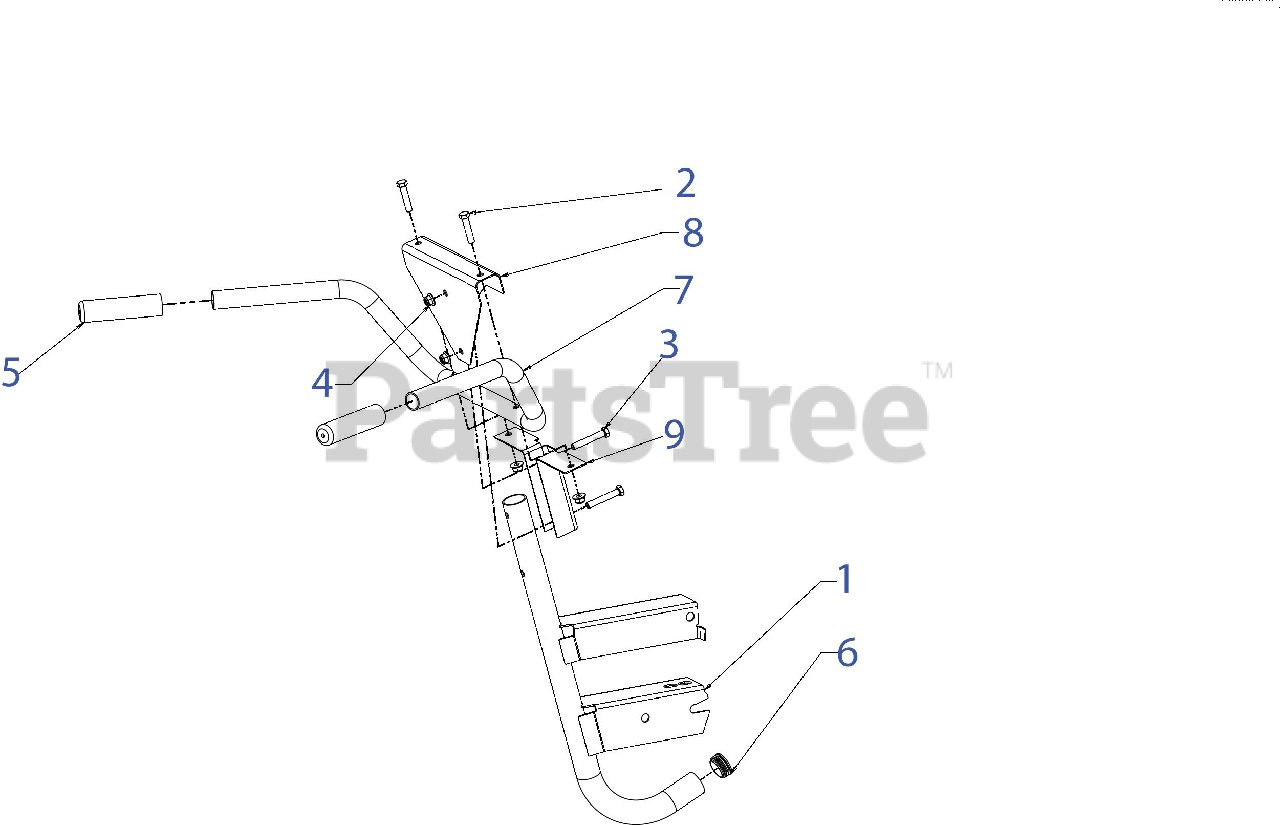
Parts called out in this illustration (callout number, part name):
1	Center Handle Tube Assembly
2	Hex Screw 3/8-16 X 1.75 Gr5
3	Screw 3/8-16 X 2.25 Gr5
5	Lapbar Grip
6	Bumper Cap
7	Top Handle
8	Top Mount Bracket
9	Center Mount Bracket
